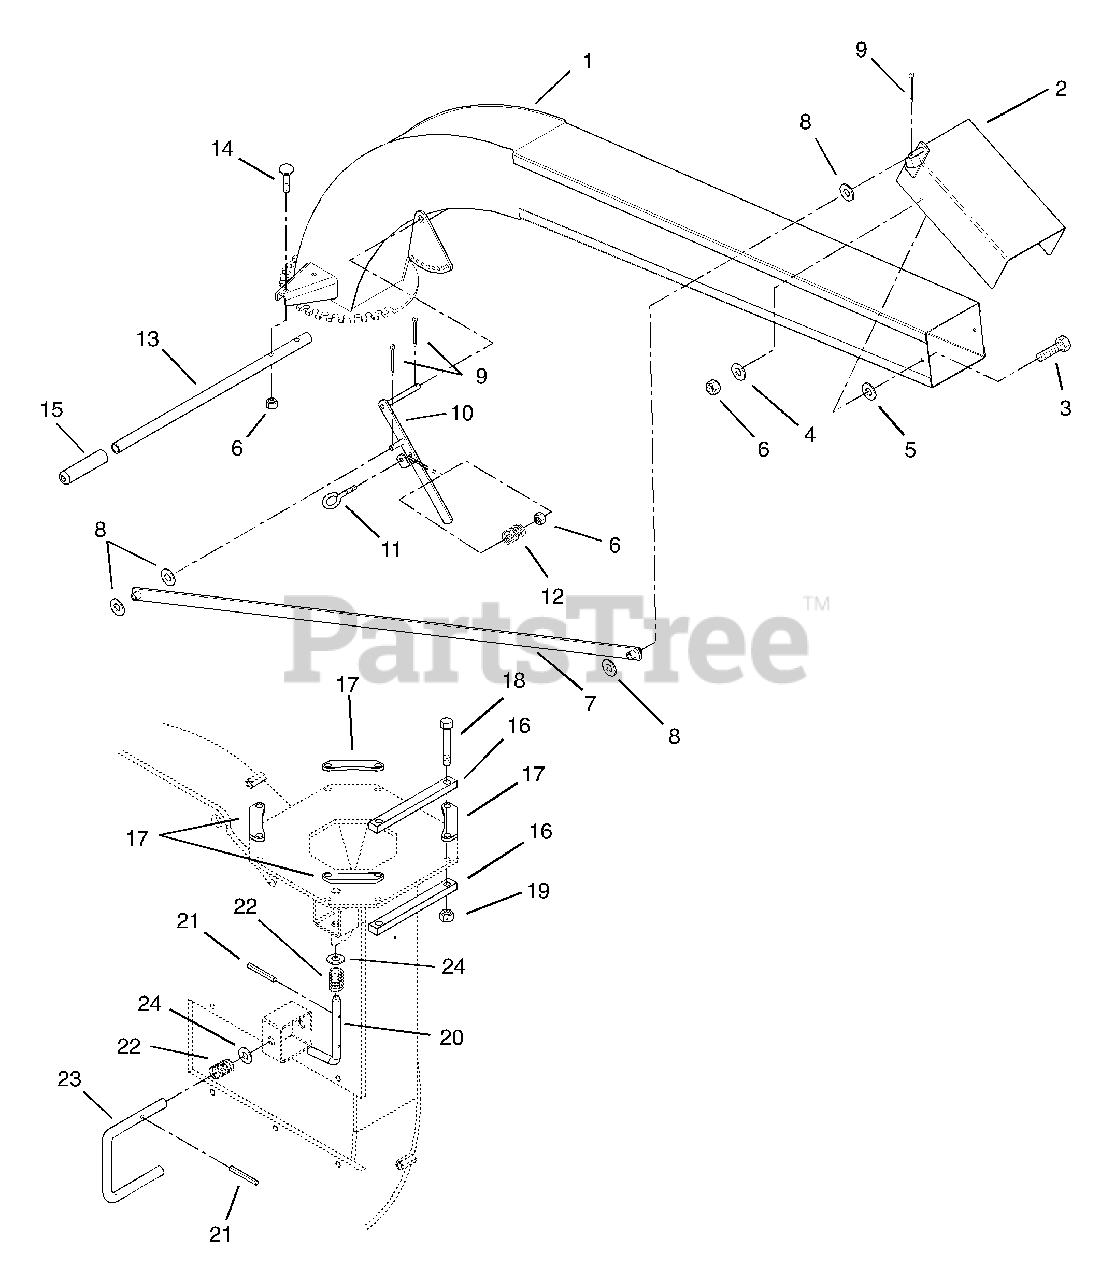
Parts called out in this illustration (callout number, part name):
1	Discharge Chute Weldment
2	Bonnet Weldment
3	Bolt-Hex .38-16 x .75 Grade 5
4	Washer-Flat-Steel .438 x 1.00 x .083
5	Washer-Flat-Nylon .38 x 1.0 x .083
6	Nut-Locking-Center .38-16
7	Control Lever Weldment
8	Washer-Flat-Steel .531 x 1.06 x .095
9	Pin-Cotter .120 x 1.0
10	Adjustment Handle Weldment
11	Eye Bolt .375-16 x 2.50
12	Spring-Compression .045 x .50 x 1.187
13	Rotation Handle
14	Bolt-Round Head Square Neck .38-16 x 2.00
15	Handle Grip
16	Clamp-Discharge Chute
17	Guide-Discharge Chute
18	Bolt-Hex .50-13 x 3.00 Grade 5
19	Nut-Locking-Center .50-13
20	Pin Index
21	Pin-Roll .188 x 1.50
22	Spring-Compression .080 x .91 x 3.38
23	Flywheel Lock Pin
24	Washer-Flat-Steel .656 x 1.31 x .095
